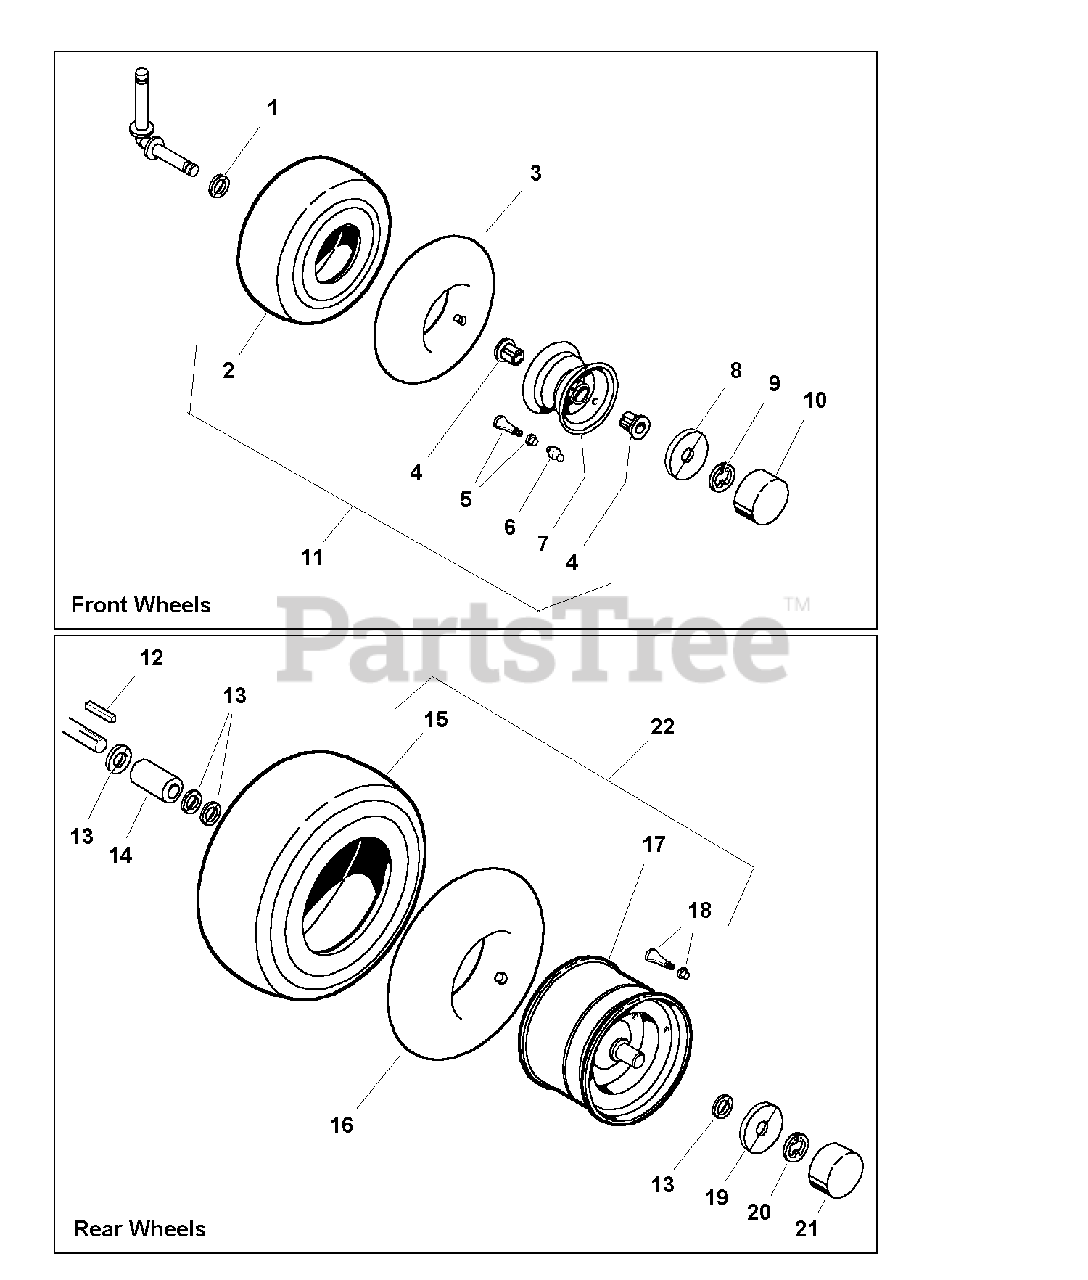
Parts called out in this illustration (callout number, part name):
1	WASHER, Special, 3/4 (Install to the inside of wheel)
2	TIRE, 15 x 6.00-6
3	TUBE, 4.10/3.50-6
4	BEARING
5	VALVE STEM & CAP
6	FITTING, Grease
7	WHEEL ASSEMBLY, (Includes Ref. No. 4)
8	RETAINER, Hub Cap, Black
9	RING, Retaining
11	WHEEL & TIRE ASSEMBLY, 15 x 6.00-6 (Includes Ref. Nos. 2, 4, 5, 6, & 7)
12	KEY
15	TIRE, 18 x 8 1/2-8
17	WHEEL ASSEMBLY
18	VALVE STEM & CAP
19	RETAINER, Cap, Hub
21	CAP, Hub, Black
22	WHEEL & TIRE ASSEMBLY, (Includes Ref. Nos. 15, 17, & 18)
